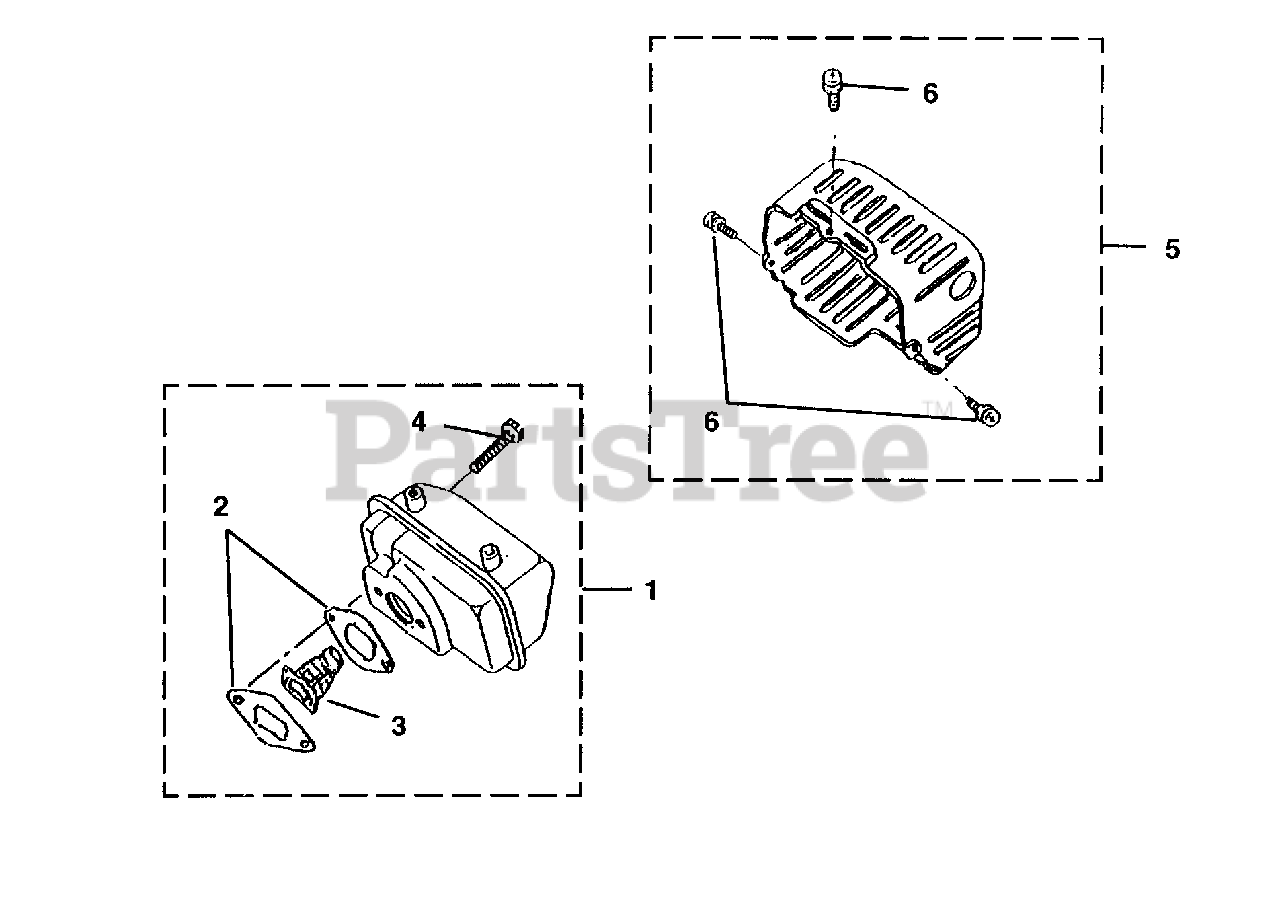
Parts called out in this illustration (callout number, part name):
1	MUFFLER ASSEMBLY
2	GASKET Muffler
3	SPARK ARRESTER
4	SCREW - Socket Hd (M6 X 60 SW)
5	MUFFLER COVER
6	SCREW (M5 x 14 W SW)
